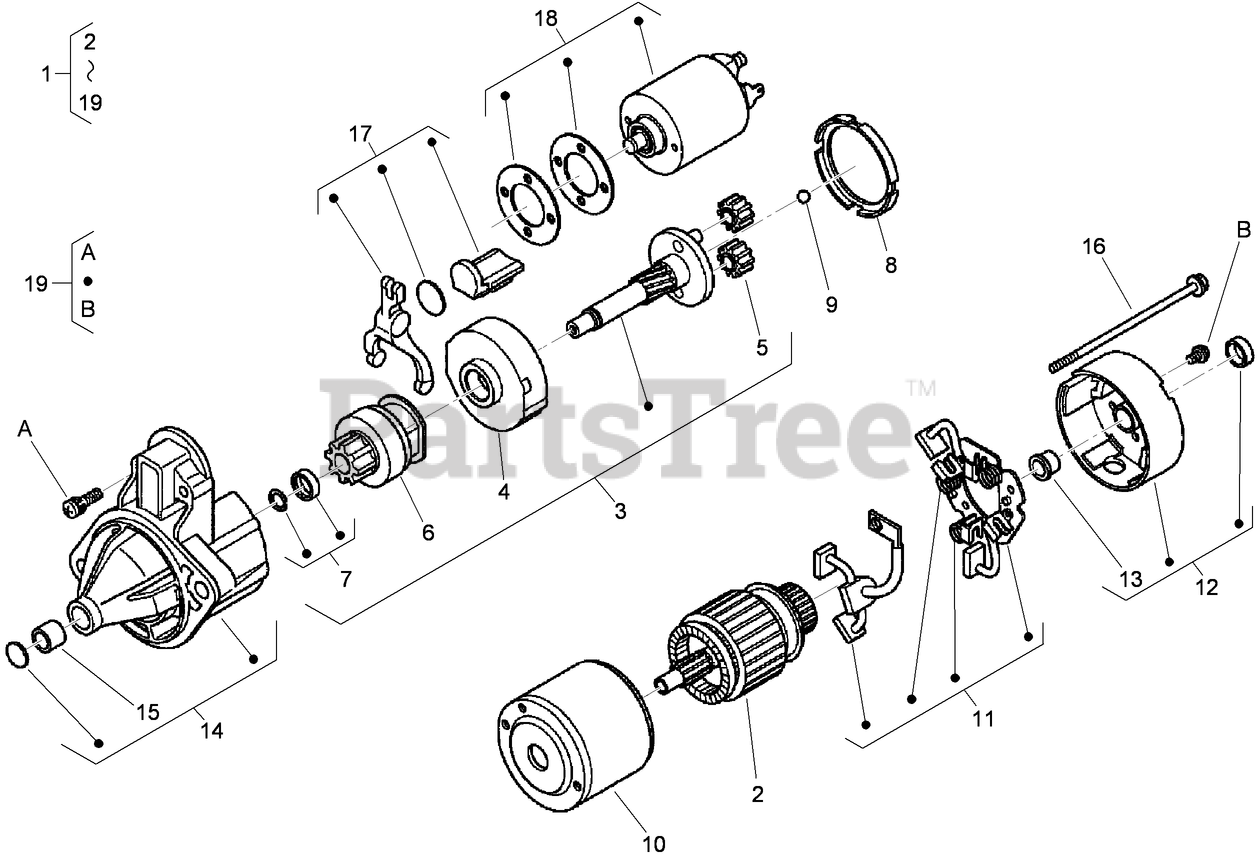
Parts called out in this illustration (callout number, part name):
1	STARTER ASM
2	ARMATURE
3	SHAFT ASM
5	GEAR-PLANETARY
6	CLUTCH-RUNNING, OVER
7	STOPPER
8	GASKET
11	BRUSH HOLDER ASM
12	REAR BRACKET ASM
13	BUSHING
14	FRONT BRACKET ASM
15	BUSHING
17	FORK LEVER ASM
18	MAGNETIC SWITCH ASM
19	SCREWS (SET OF 4)
